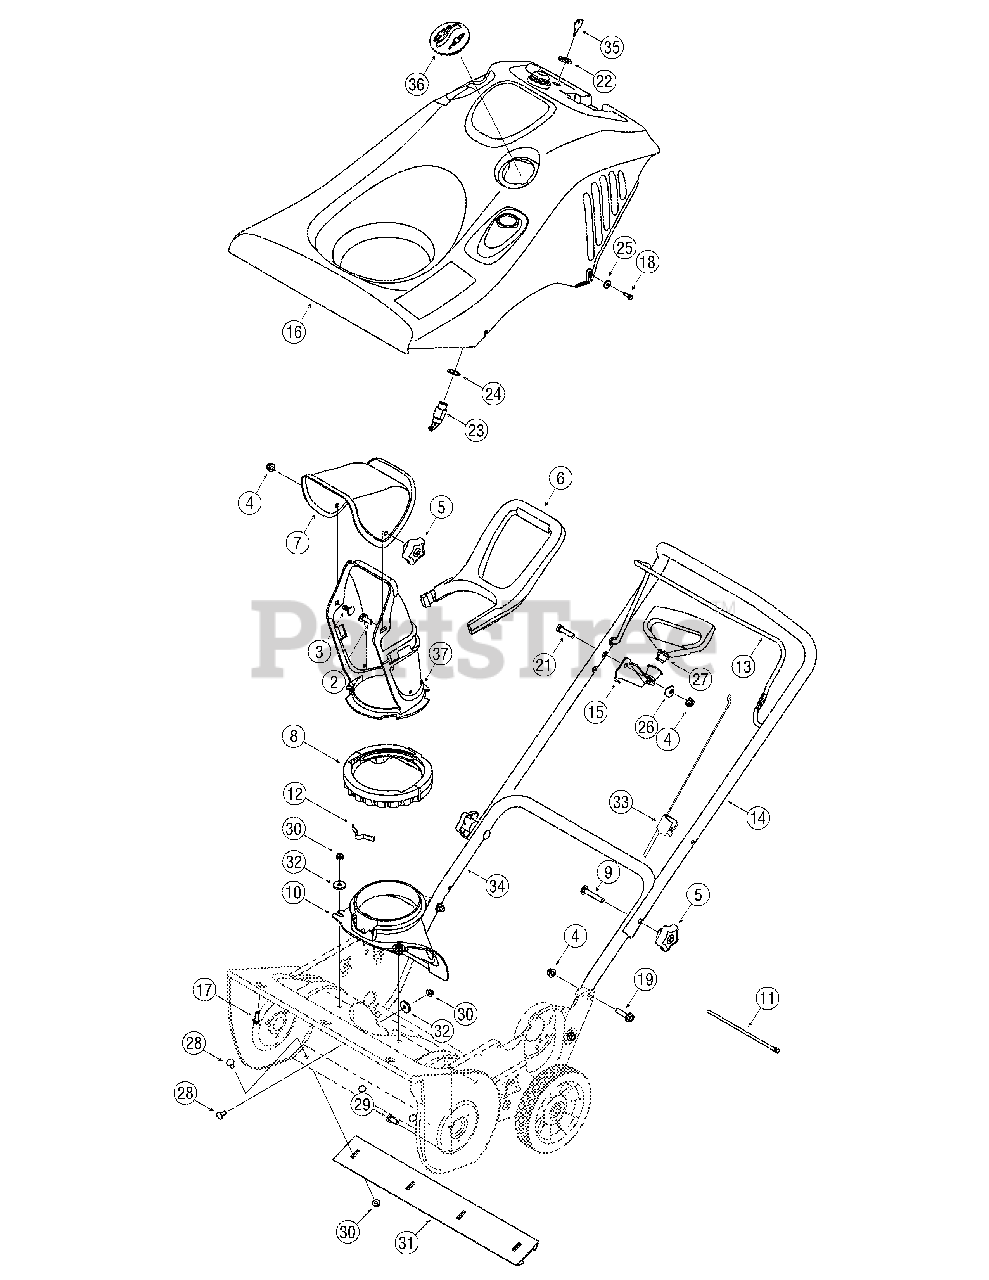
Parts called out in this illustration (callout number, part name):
1	Chute Assembly (Incl. Ref. 37-41)
2	Carriage Bolt 5/16-18 x 1.0"
3	Carriage Bolt 5/16-18 x 0.750"
4	Flange Lock Nut, 5/16-18
5	Star Knob Assembly
7	Upper Chute
8	Ring-Lower Chute
9	Carriage Bolt 5/16-18 x 2.0 Gr. 5
10	Chute, Adapter 5" Dia
12	Chute Adjustment Spring
15	Mitten Grip Bracket
16	Shroud Assembly, Gray (Incl. Spark Plug Cover)
17	Screw, 1/4-15 x .75
18	Self-tapping Screw, #10-16 x .625"
19	Hex Flange Screw, 5/16-18 x 1.25
20	Hex Flange Screw 5/16-18 x 1.50 Gr. 5
21	Hex Screw, 5/16-18 x 1.375
22	Hex Nut 5/8-32 x .12 Special
23	Key Switch-Electric Start
24	Lock Washer Internal .625 x 1.058
25	Flat Washer .194" x .62" x .063
26	Saddle Washer .320 x .93
27	Recoil Handle, Mitten
28	Screw, 1/4-20 x .62
29	Truss Machine Screw, 5/16-18 x .75
30	Hex Flange Lock Nut, 1/4-20
31	Shave Plate, 19.88
32	Flat Washer .265 x .938 x .120
33	Control Cable
35	Ignition Key
36	Spark Plug Cover
37	Lower Chute 5" Dia.
